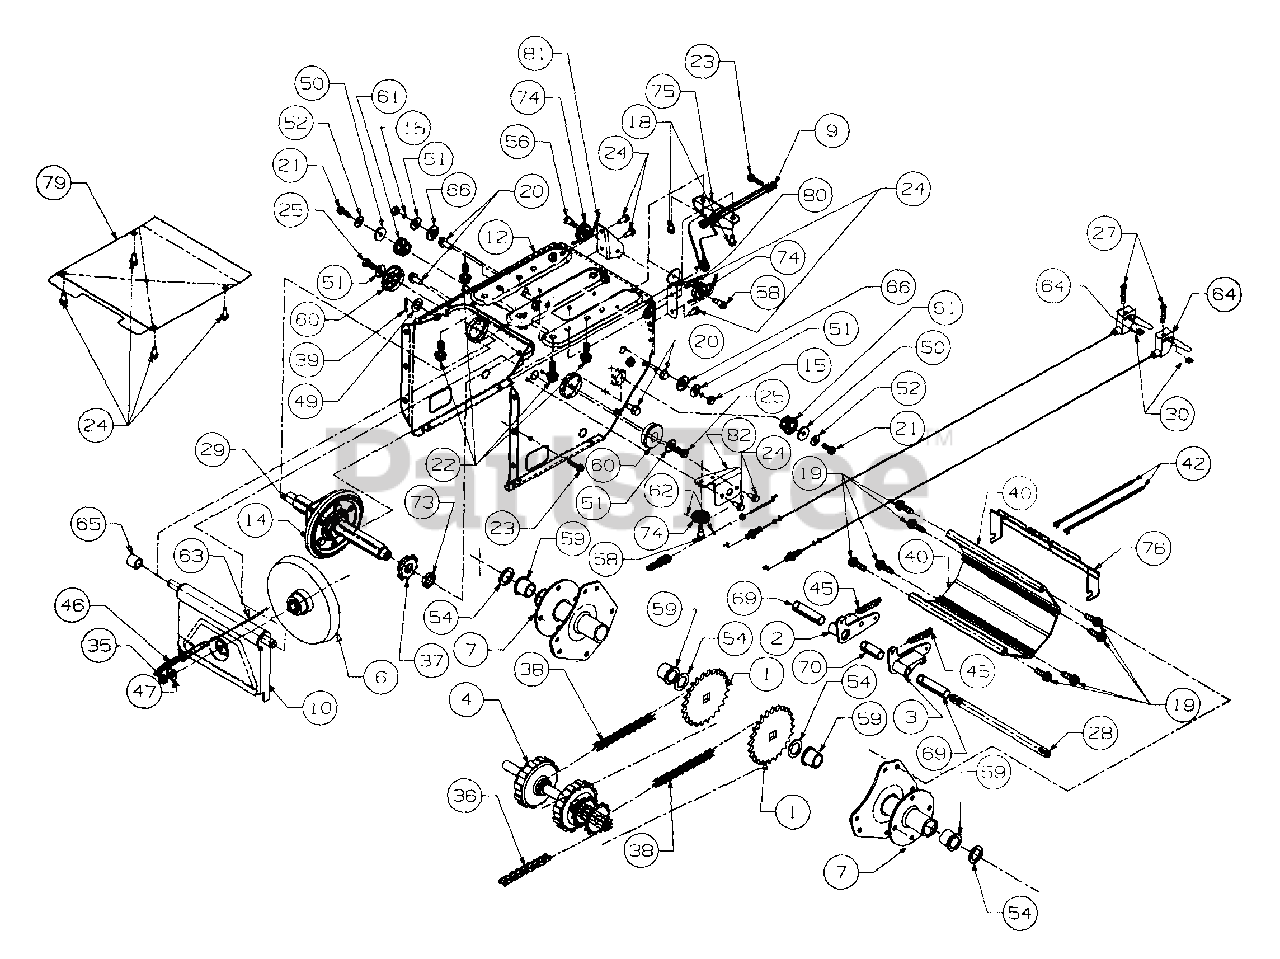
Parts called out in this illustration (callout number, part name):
1	Axle Assembly
2	Dog Assembly - R.H.
3	Dog Assembly - L.H.
4	Shaft Assembly
6	Disc Assembly
14	Wheel Assembly Friction
15	Screw
18	Screw
19	Screw
20	Screw
21	Screw
23	Screw
24	Screw
25	Screw
27	Screw
28	Shaft
29	Shaft
30	Nut Flange
35	Nut Jam
36	Chain
37	Sprocket
38	Chain
39	Pin Cotter
40	Housing Track
42	Cable Tie
45	Spring
46	Spring
47	Washer-Bell
49	Washer-Flat
50	Washer-Flat
51	Washer-Bell
52	Washer-Bell
54	Washer-Flat
56	Lubricant
58	Screw-Shoulder
59	Bearing-Flange
60	Bearing Ball
61	Bearing-Hex Flange
62	Cable-Auger Clutch
63	Cable-Drive Clutch
64	Cable with Trigger Lever
65	Spacer
66	Spacer-Shoulder
69	Spacer-Split
70	Spacer-Split
73	Spacer
74	Roller-Cable
